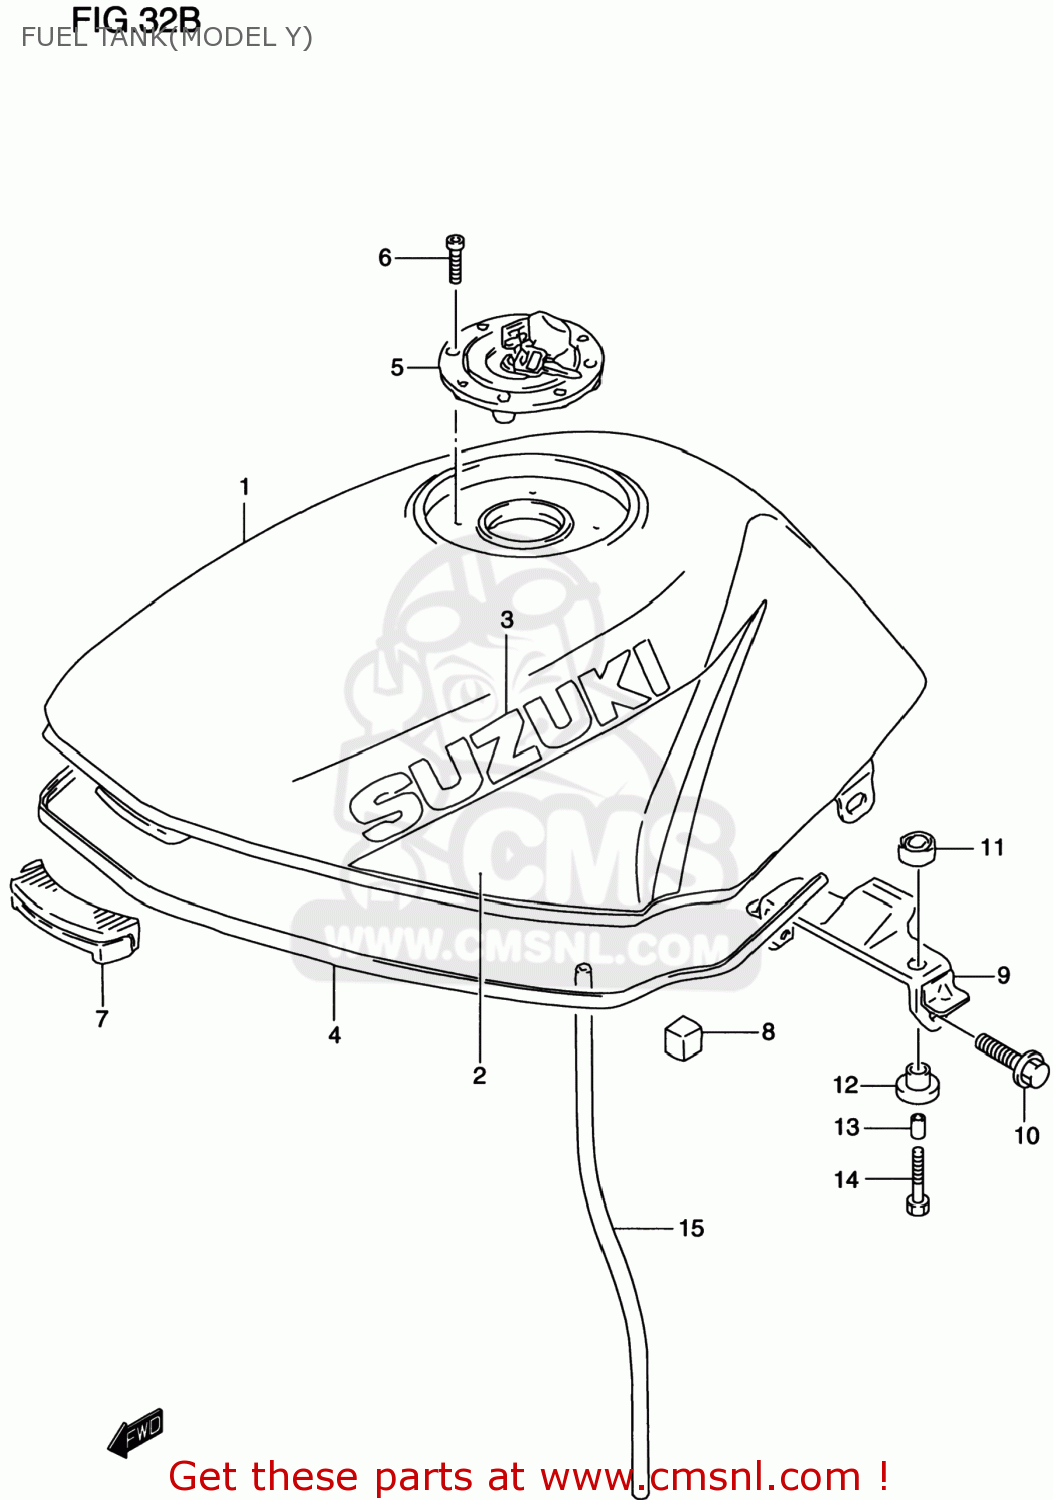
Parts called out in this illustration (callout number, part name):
1	TANK ASSEMBLY,FUEL
2	TAPE SET,FUEL TANK
3	EMBLEM,FUEL TANK
4	MOLDING
5	CAP SET,FUEL
6	BOLT(5X20)
7	CUSHION,FUEL TANK FR
8	CUSHION,FUEL TANK SIDE
9	BRACKET,FUEL TANK RR
10	BOLT
11	CUSHION
12	CUSHION
13	SPACER(6.5X9X18)
14	BOLT(6X30)
15	HOSE,WATER DRAIN
